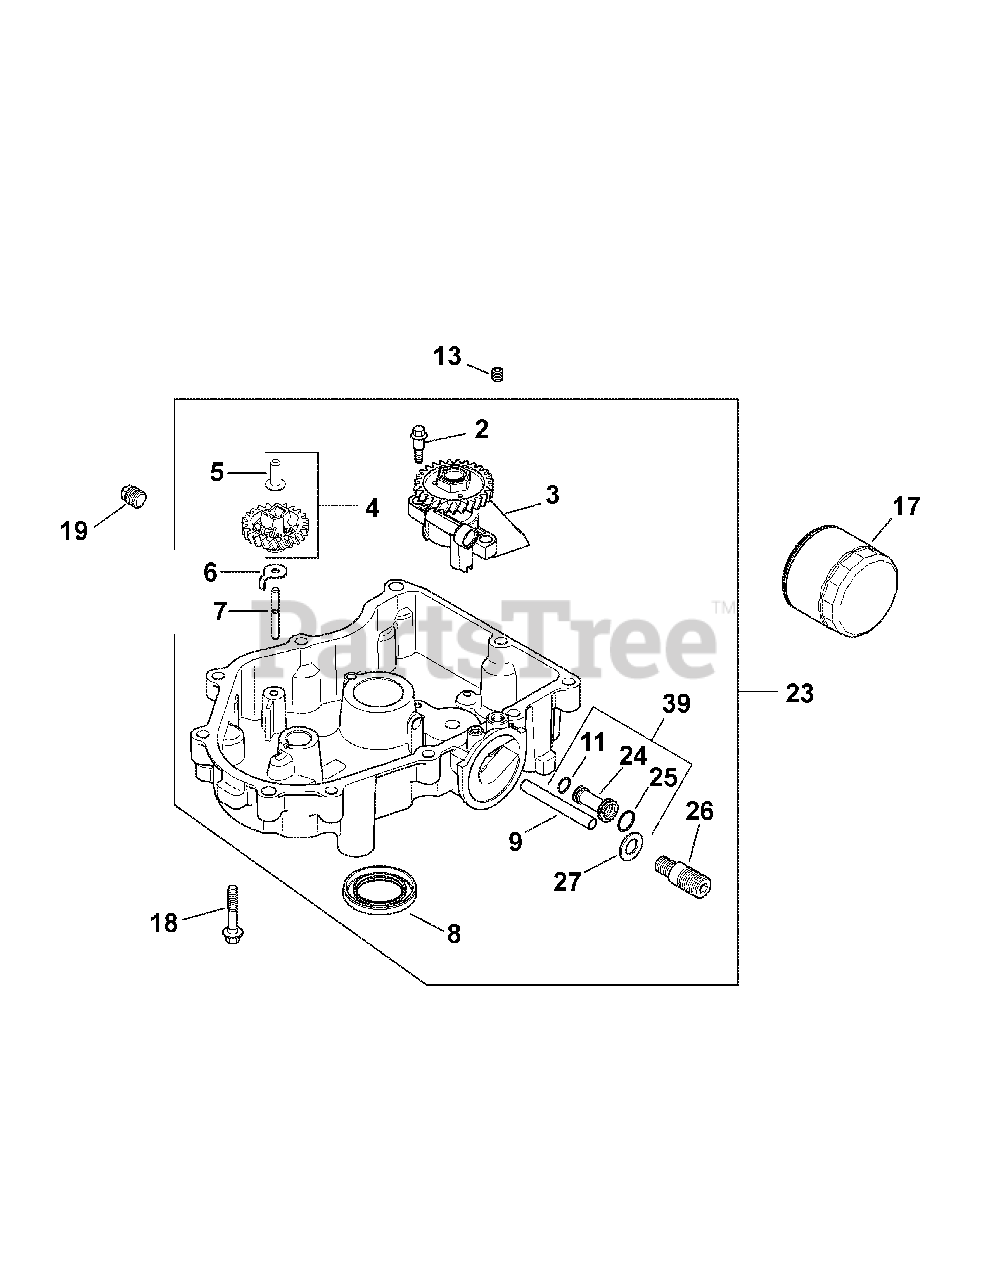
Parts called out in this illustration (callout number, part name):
2	Shd. Thd. Frm. Screw, M6 x .0 x 6.5
3	Oil Pump Assembly
4	Governor Gear Kit w/ Pin
5	Governor Regulating Pin
7	Governor Gear Shaft
9	Oil Feed Tube - Filter To Pan
11	Oil Pick-Up O-Ring
13	Ctsk. Pipe Plug, 1/8
18	Flg. Screw, M8 x 1.25 x 45
19	Sq. Hd. Pipe Plug, 3/8
23	Oil Pan Assembly
24	Oil Feed Tube
26	Oil Filter Nipple
39	Oil Feed Tube Assembly
